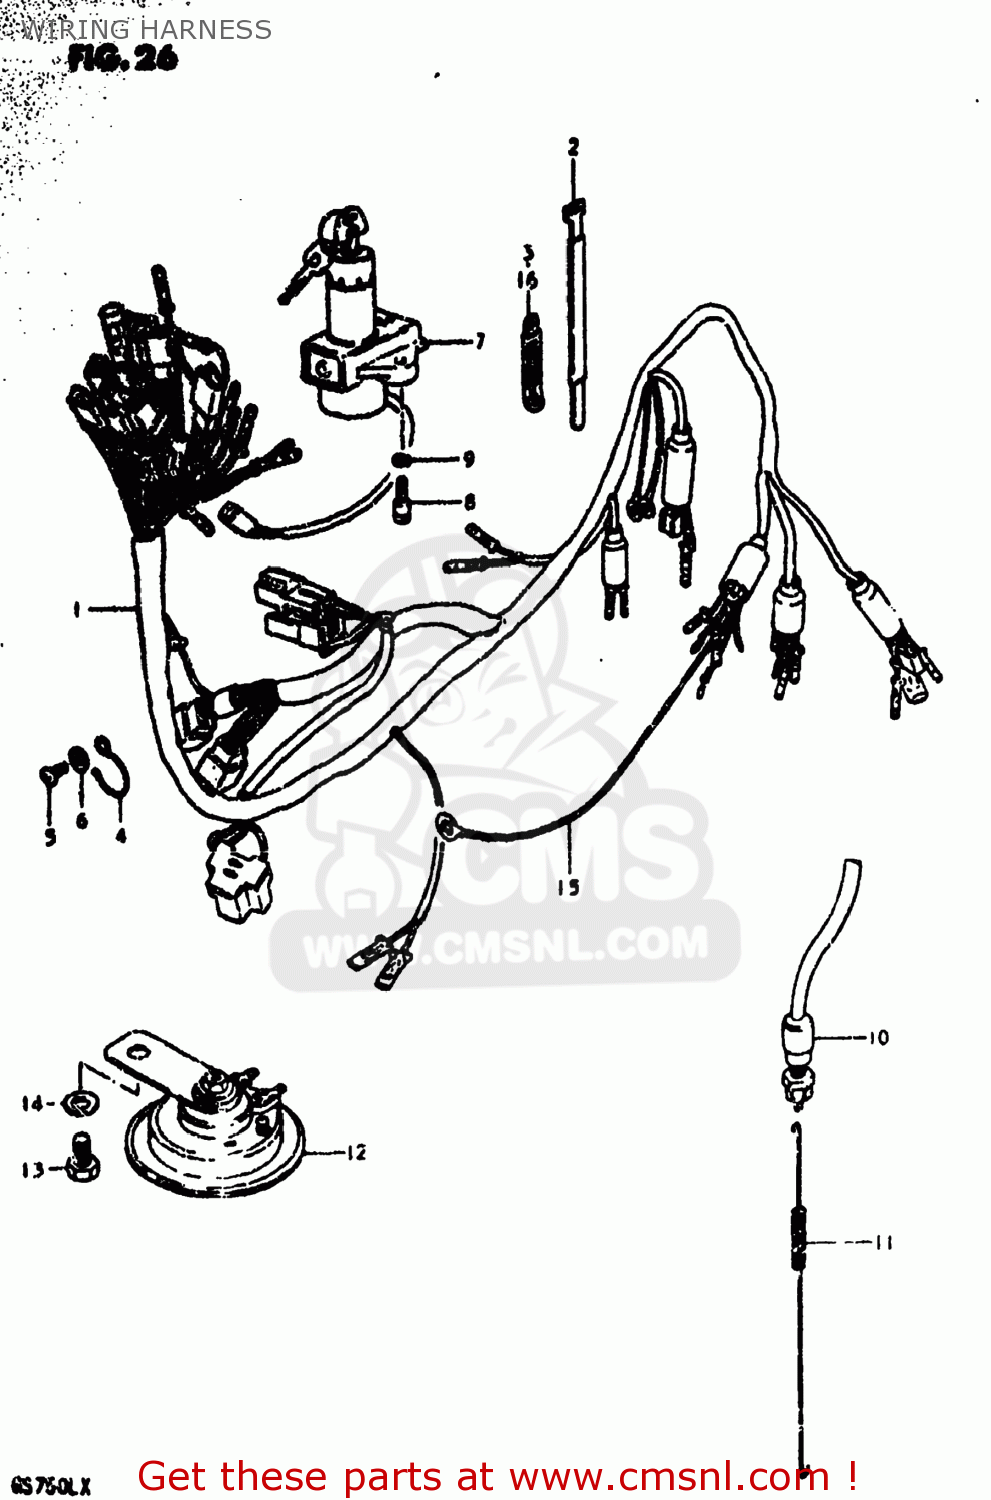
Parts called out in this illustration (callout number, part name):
1	HARNESS,WIRING
2	CLAMP
3	CLAMP
4	GUIDE,WIRING HARNESS
5	SCREW 6X12
6	WASHER
7	LOCK ASSEMBLY,STEERING
8	BOLT
9	LOCK WASHER
10	SWITCH ASSEMBLY,STOP LAMP
11	SPRING
12	HORN ASSEMBLY,LOW PITCH
13	HORN ASSEMBLY
14	BOLT 8X12
15	WASHER
16	WIRE
17	CLAMP
